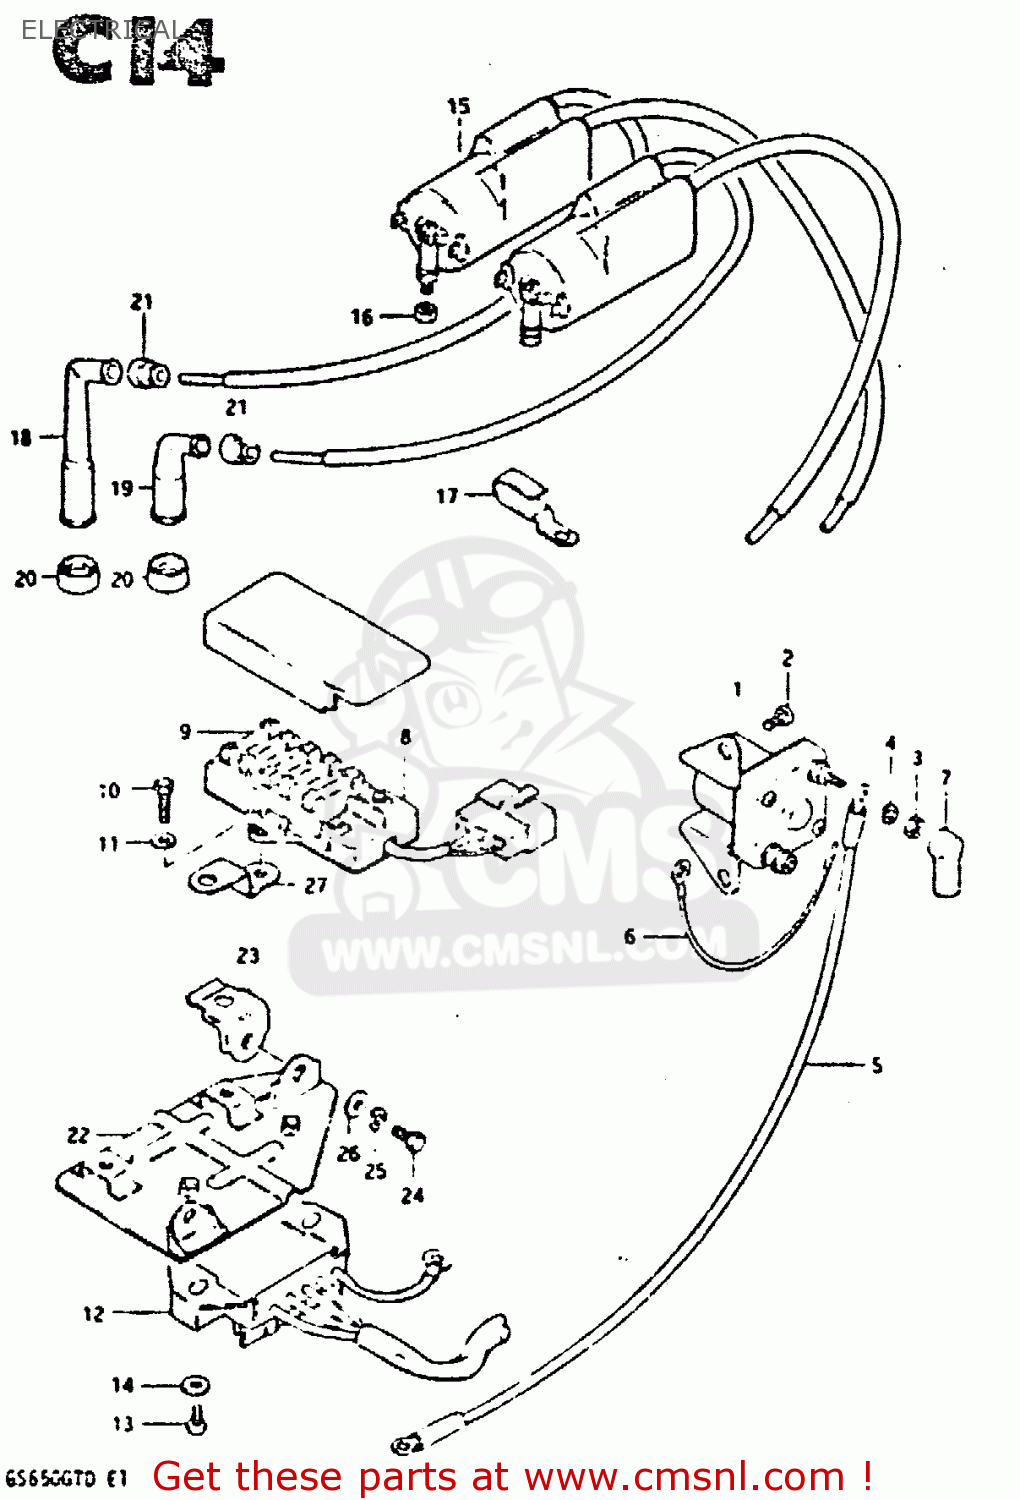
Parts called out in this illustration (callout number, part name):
1	RELAY ASSY,STARTING MOTOR
2	SCREW
3	NUT 6MM
4	LOCK WASHER
5	CABLE,STARTING MOTOR
6	LEAD WIRE
7	CAP,STARTER RELAY
8	BOX ASSEMBLY,FUSE
9	FUSE(15A)
10	BOLT, UPPER
11	WASHER
12	RECTIFIER ASSEMBLY
13	SCREW
14	WASHER
15	COIL ASSEMBLY,IGNITION
16	NUT
17	CLAMP
18	CAP ASSY,SPARK PLUG
19	CAP,SPARK PLUG
20	SEAL,SPARK PLUG CAP
21	SEAL,SPARK PLU
22	PLATE,ELECTRIC PARTS H
23	BRACKET, PARTS HOLDER
24	BOLT
25	LOCK WASHER
26	WASHER
27	BRACKET
